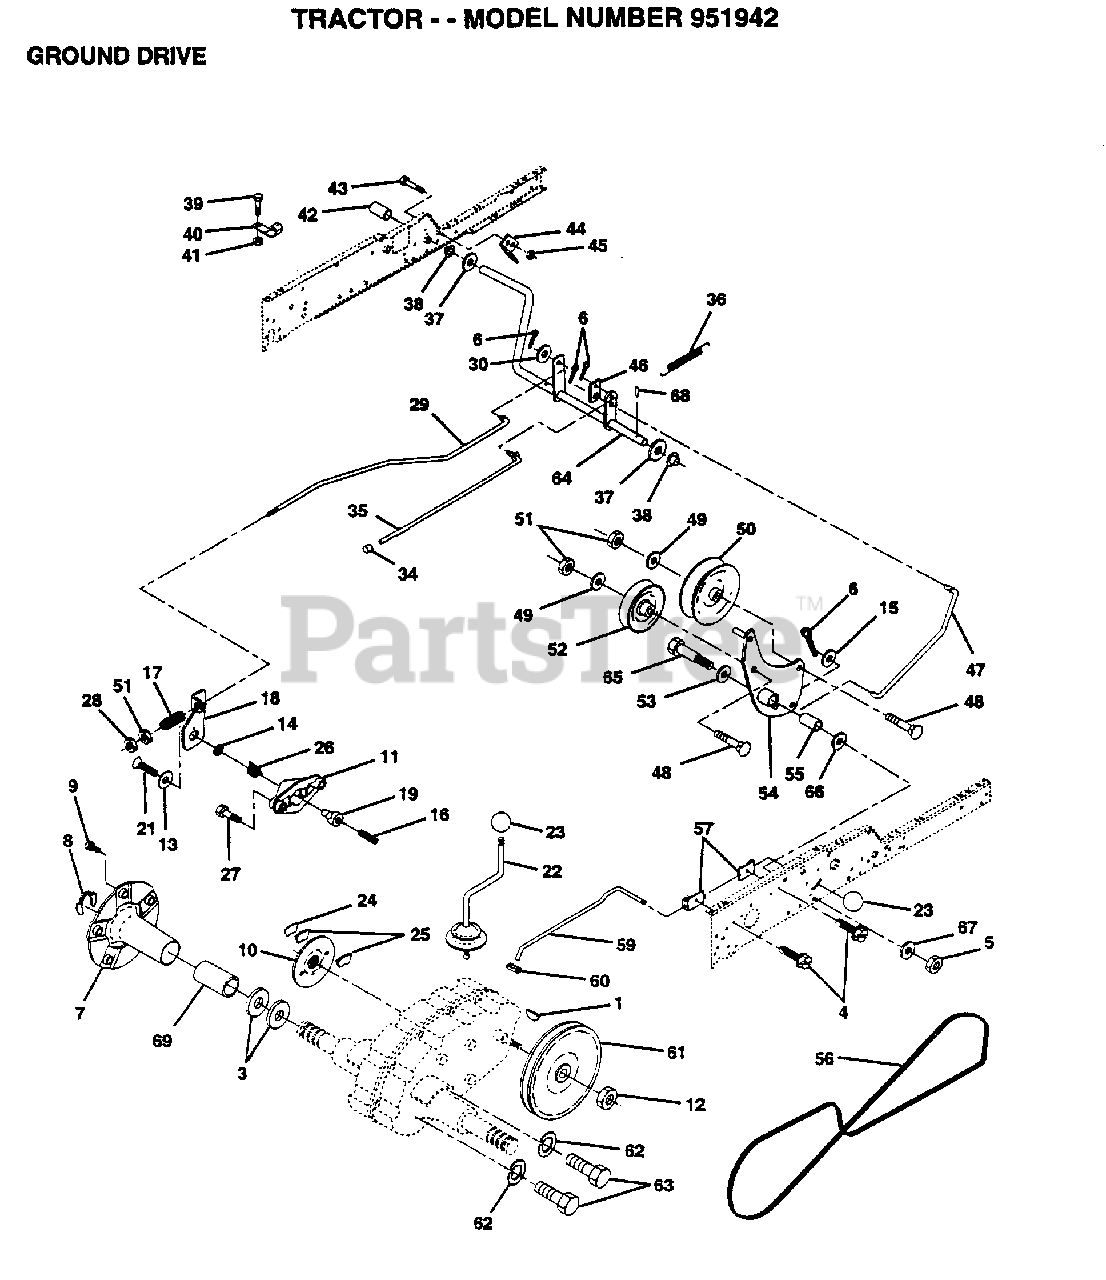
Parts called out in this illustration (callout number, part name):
3	WASHER T
4	SCREW LT
6	COTTER PIN
8	KLIP RING
9	BOLT.HUB.WHL.REAR
10	BRAKE.DISC.
11	YOKE BRAKE DISC
12	NUT STD
13	WASHER SPECIAL
14	BUSHING LEVER BKT
15	WASHER
16	SCREW SET 1/4-20
17	"SPRING,ROD BRAKE"
18	LEVER BRAKE GT
19	CAM BRAKE DISC GT
21	SCREW FLT 1/4X28
22	GEAR SHFT LVR T
23	KNOB
24	SUPPORT PUCK BRKE
25	PUCK BRAKE TOP
26	SPRING RET BRAKE
27	SCREW HX WASH
28	NUT
29	ROD BRAKE ZINC GT
30	WASHER
34	PLUNGER CAP T
35	ROD BRAKE PART GT
37	WASHER
38	NYLINER T
39	SCREW
40	ACT-SWITCH T
42	PEDAL COVER T
43	BOLT LT
44	BRKT SWITCH GT
45	NUT
46	RETAINER.SPRING
47	ROD.CLUTCH
48	BOLT
49	WASHER
50	FLAT IDLER PULLEY
52	PULLEY.IDLER.V.GR
53	WASHER T
54	ARM.ASM.IDLER.CLU
55	"LY, BEARING"
56	BELTV.GR.DR.83.
57	BRACKET.ROD.SHIFT
59	ROD SHIFT HI LO
60	CONNECTING LINK
62	LOCKWASHER
63	BOLT
65	AXLE BOLT
66	WASHER.HARD.BLADE
67	WASHER
68	ROLL PIN STD
69	"COVER, HUB"
